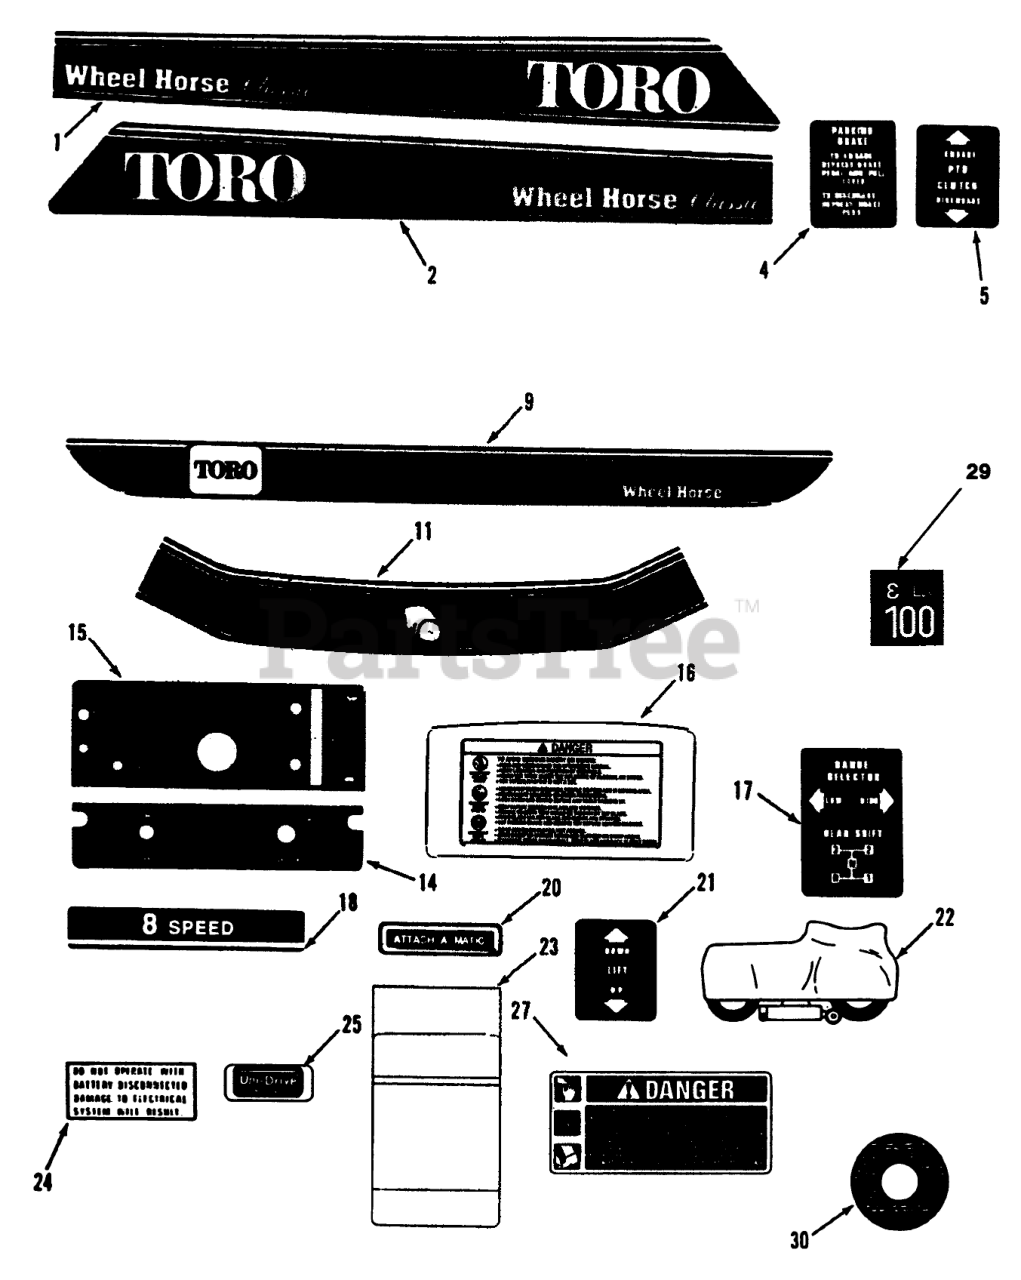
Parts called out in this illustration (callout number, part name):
1	DECAL-HOOD CLASSIC
2	DECAL-HOOD CLASSIC
4	DECAL-PARKING, BRAKE
5	DECAL PTO CLUTCH
9	DECAL-FENDER
11	DECAL-FRONT HOOD
14	Decal-Switch Plate
15	DECAL-LOWER DASH
16	Decal-Danger
17	DECAL-SHIFT PATTERN
18	DECAL-312 8-SPEED
20	Decal-Attac-O-Matic
21	DECAL-LIFT
22	Vinyl Tractor Cover
23	MAINTENANCE-DECAL
24	DECAL ELECT SYSTEM
25	Decal-Unidrive
27	DECAL-DANGER
29	DECAL-EUROPE
30	Decal-Air Cleaner
